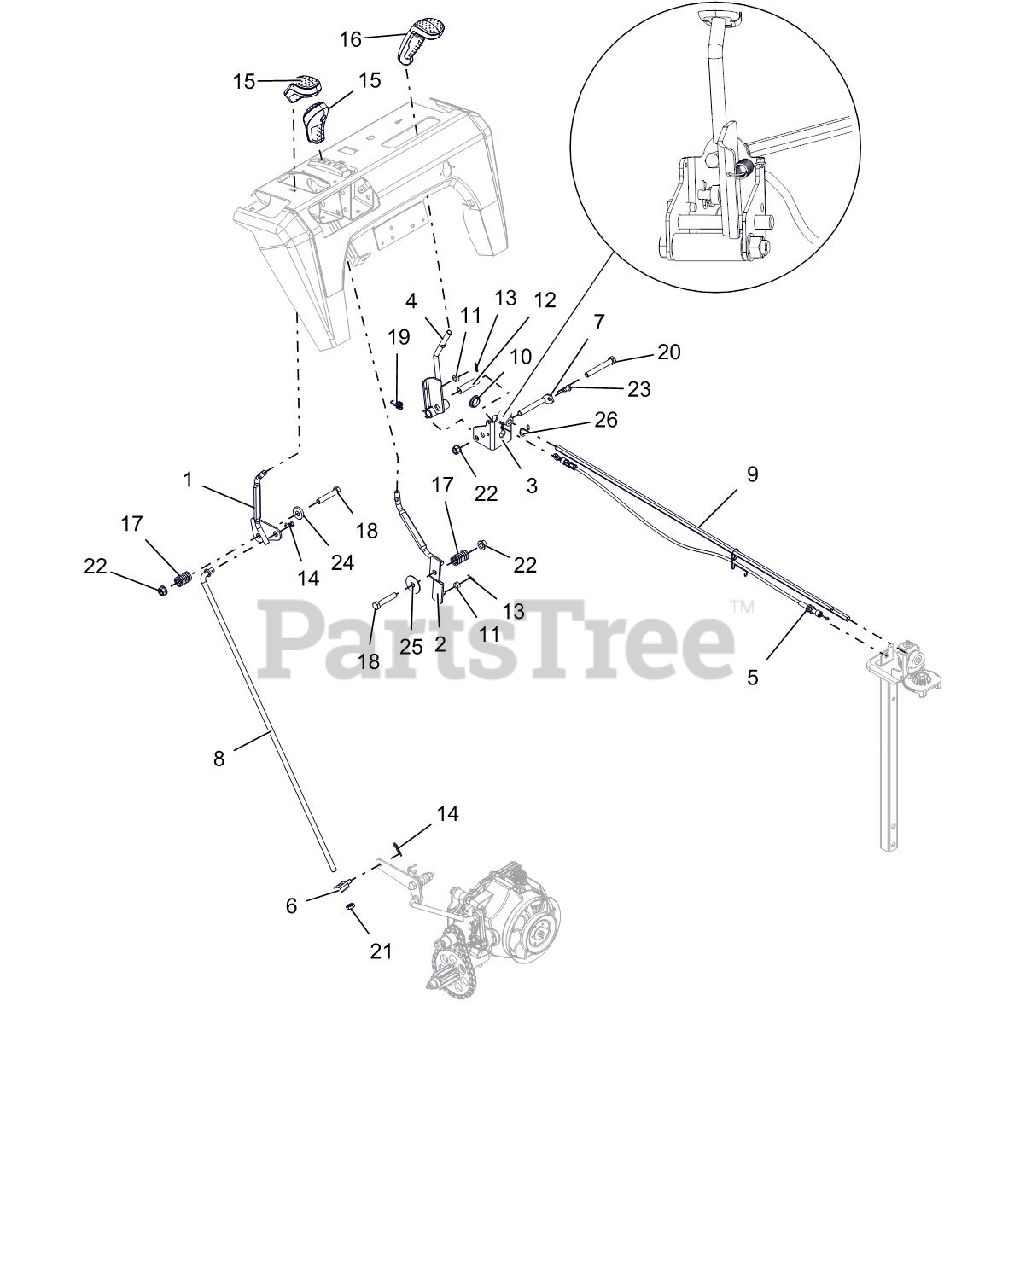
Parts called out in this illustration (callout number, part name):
1	WELDMENT,LG DASH SPEED CONTROL
2	WELDMENT,LG DASH DEFL CONTROL
3	WELDMENT-CONTROL BRACKET-CHUTE
4	WELDMENT,LG DASH QT CONTROL
5	CABLE, CHUTE LOCK, PRO
6	PIVOT,SHIFT ROD .375-16(TRUNN)
7	ROD, PIVOT - INTERLOCK
8	ROD, SHIFT-PRO
9	ROD, HEX - CHUTE ROTATION
10	BUSHING, POLYLINER-.75 SNAPIN
11	BSHG-SLV .265X.500X.219
12	SPCR, WHEEL .385X.500X2.00
13	PIN-HAIR INT .06X.18X.77
14	PIN-HAIR INT .08X.18X1.18 YWZC
15	KNOB, CONTROL, DASH
16	HANDLE, QUICK TURN, ASM
17	SG-COMP .125X.781X1.250
18	@BLT-HEX .38-16X2.00 GR5 YWZC
19	SPRING-EXT .047X.438X1.45
20	@BLT-HEX .38-16X2.75 GR5 YWZC
21	NUT-HEX-JAM .375-16 YWZC
22	@NUT-LK-TOP-FLG .38-16 YWZC
23	SCR-TAP .25-20X.50 HWH TR YWZ
24	WSHR-FL-STL .406X1.00X.188 YWZ
25	WSHR-FL-STL .380X1.50X.062 YWZ
26	E-RING .750X.050
